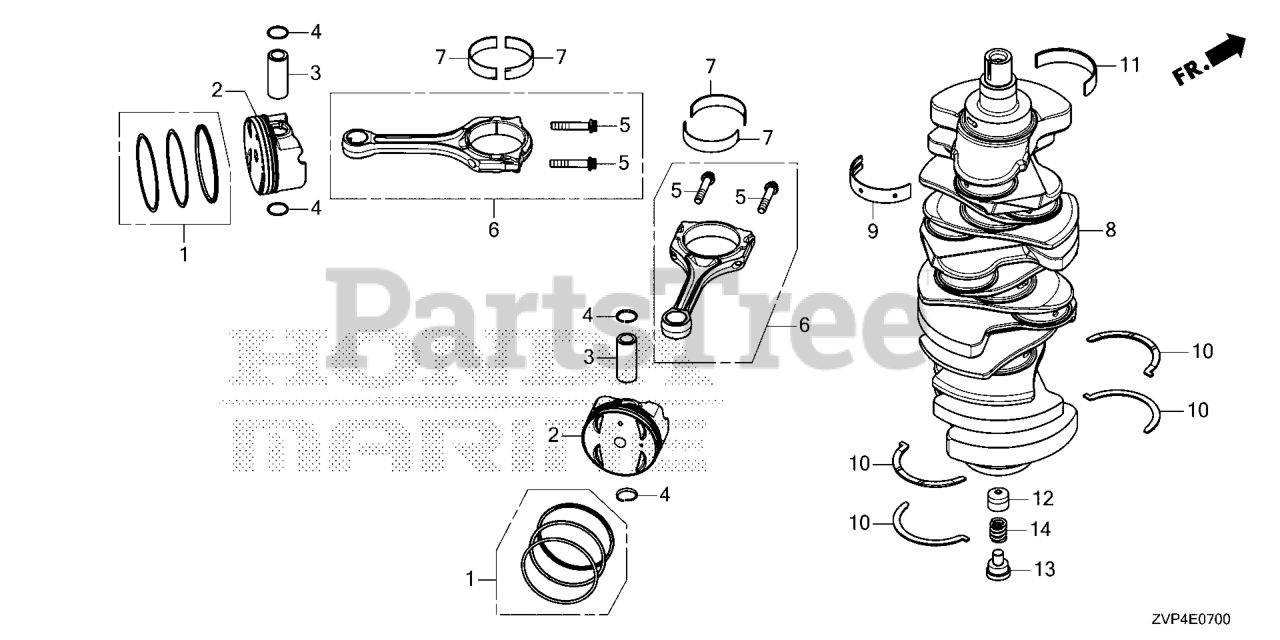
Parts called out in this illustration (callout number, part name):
1	RING SET (STD)
3	PIN, PISTON
4	CLIP, PISTON PIN
5	BOLT, CONNECTING ROD
6	CONN ROD COMP
7	BRG A, CONN ROD
7	BRG B, CONN ROD
7	BRG C, CONN ROD
7	BRG D, CONN ROD
7	BRG E, CONN ROD
8	CRANKSHAFT
9	BRG A, MAIN (UPPER)
9	BRG B, MAIN (UPPER)
9	BRG C, MAIN (UPPER)
9	BRG D, MAIN (UPPER)
9	BRG E, MAIN (UPPER)
9	BRG F, MAIN (UPPER)
10	WASHER, THRUST
11	BRG A, MAIN (LOWER)
11	BRG B, MAIN (LOWER)
11	BRG C, MAIN (LOWER)
11	BRG D, MAIN (LOWER)
11	BRG E, MAIN (LOWER)
11	BRG F, MAIN (LOWER)
12	RETAINER, SPG
13	SEAT, SPG (350)
14	SPRING, SUPPORT
